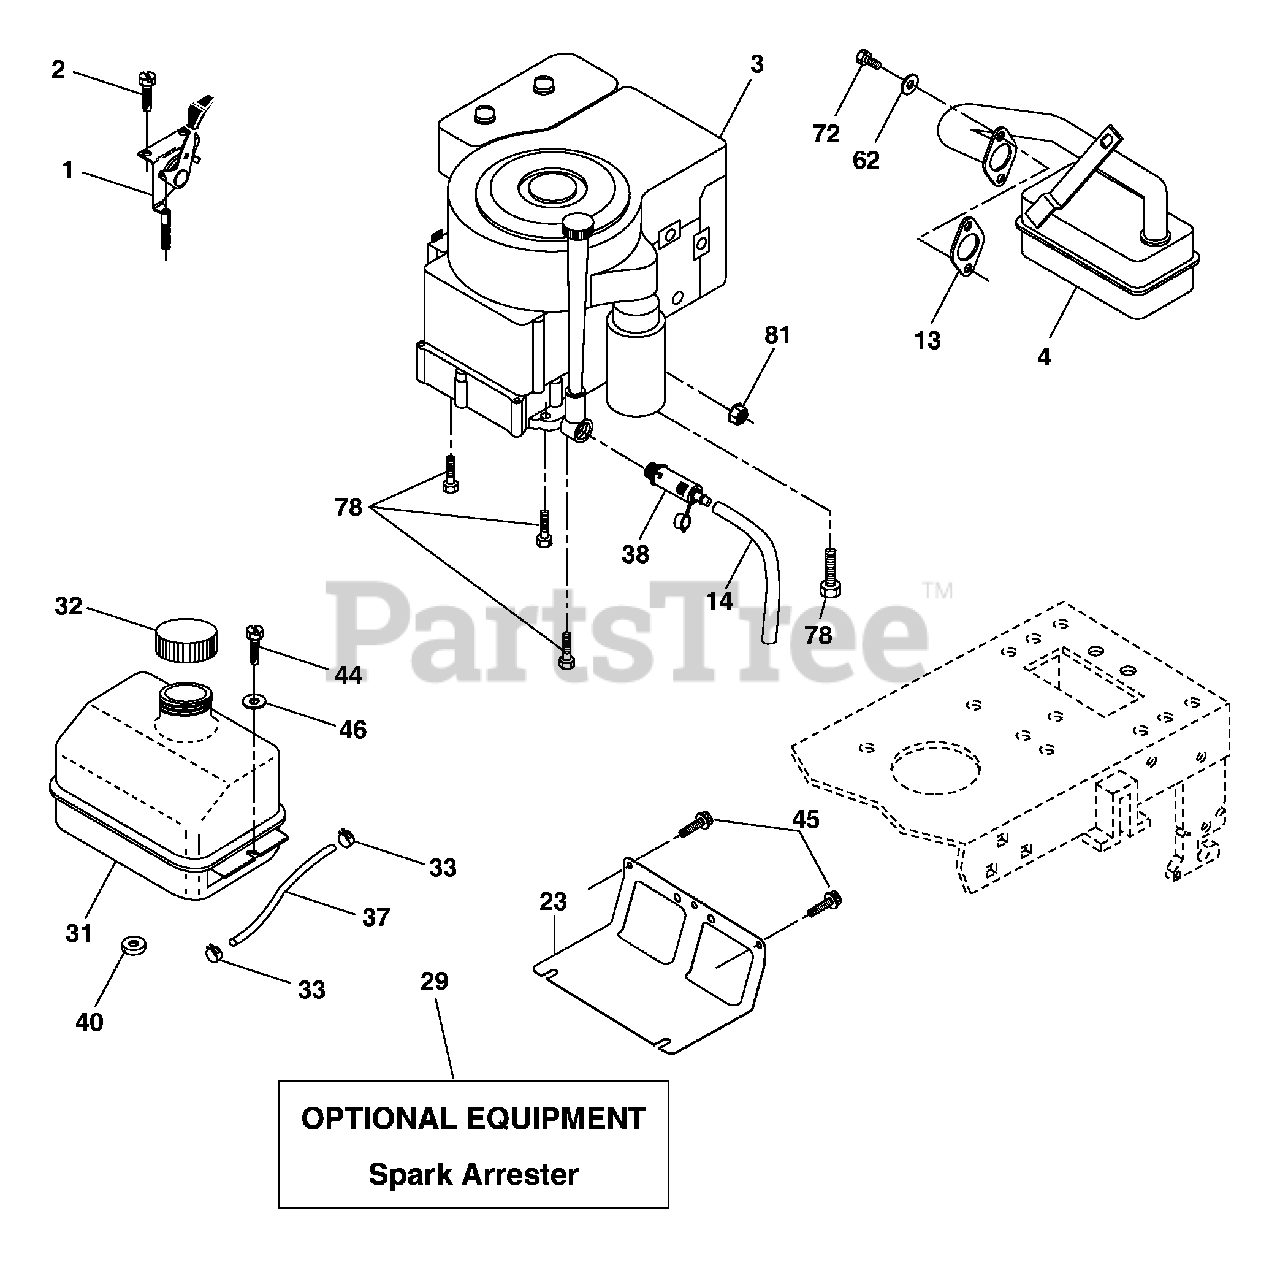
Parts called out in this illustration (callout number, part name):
1	Control Th/ch Flag
2	Screw Hex Thd Cut 1/4-20 x 1/2
4	Muffler Exhaust B&S
13	Gasket Eng 1 313 Id Tin Plated
14	Tube Drain Oil Easy
23	Shield BRN/DBR Guard
29	Kit Spark Arrestor (Flat Scrn)
31	Tank Fuel Front
32	Cap Asm Fuel
33	Clamp Hose
37	Line Fuel 20"
38	Plug Drain Oil
40	Bushing Snap Nyl Blk Fuel Line
44	Screw Thdrol 1/4-20 x 3/4
45	Screw Hex Wsh Thdrol 3/8-16
46	Washer 9/32 x 7/8 x 16 Ga.
62	Washer Split
72	Screw Hex Hd Cap 5/16-18 x 3/4
78	Screw 3/8-16 x 1-1/4
81	Nut Keps Hex 1/4-20 unc
